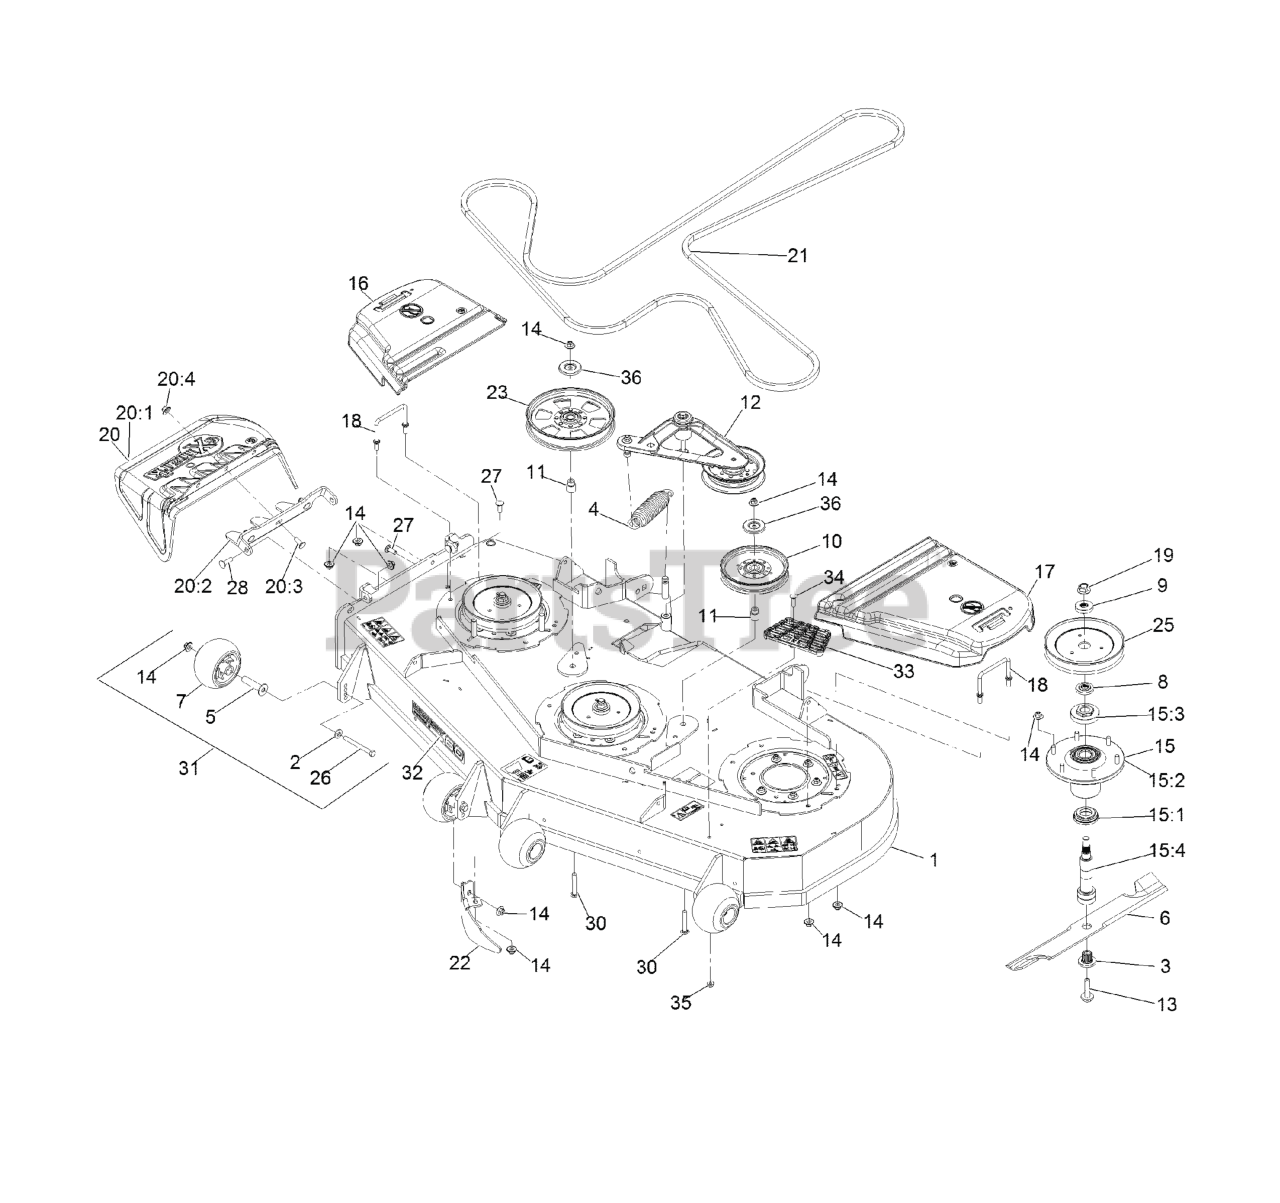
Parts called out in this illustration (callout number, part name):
1	DECK ASM,W/DECALS 60
2	WASHER-BELLEVILLE
3	BUSHING,SPLINED
4	SPRING-EXTENSION
5	AXLE, ROLLER
6	Blade-Extreme 2, 20.50"
7	ROLLER-SCALP, ANTI
8	SPACER,SPLINED STEPPED
9	SPACER,SPLINED
10	IDLER-PULLEY
11	BUSHING-IDLER
12	DECK IDLER ASM
13	SCREW,SEMS 1/2-20 X 2.19
14	Nut-Nyloc 3/8-16 Flg
15	ASM,SPINDLE HOUSING
15:1	GUARD,BOTTOM
15:2	ASM,CUTTER HOUSING
15:3	NUT, SPINDLE 7/8-14
15:4	SPINDLE,DOUBLE SPLINE
16	COVER-BELT, RH
17	COVER-BELT, LH
18	WIREFORM-COVER
19	NUT-FLANGE, CENTERLOCK
20	ASM,DISCHARGE CHUTE
20:1	CHUTE,DISCHARGE
20:2	BRACKET,DISCHARGE CHUTE
20:3	SCREW-CARR
20:4	Nut-Nyloc 3/8-16 Flg
22	DOGLEG - LZ60
23	PULLEY-IDLER, FLAT
25	SHEAVE,BLADE DRIVE 7.25
26	SCREW-HH 3/8-16 X 3 3/4 GR 8
27	SCREW-CARR
28	Bolt-Carriage 3/8-16 X 1 1/4
30	SCREW-CARR
31	KIT, ANTI-SCALP ROLLER
32	DECAL, 606
33	STEP-DECK
34	Bolt-Carriage 5/16-18 X 1 1/4
35	NUT-HF, NI
36	SHIELD-DUST
